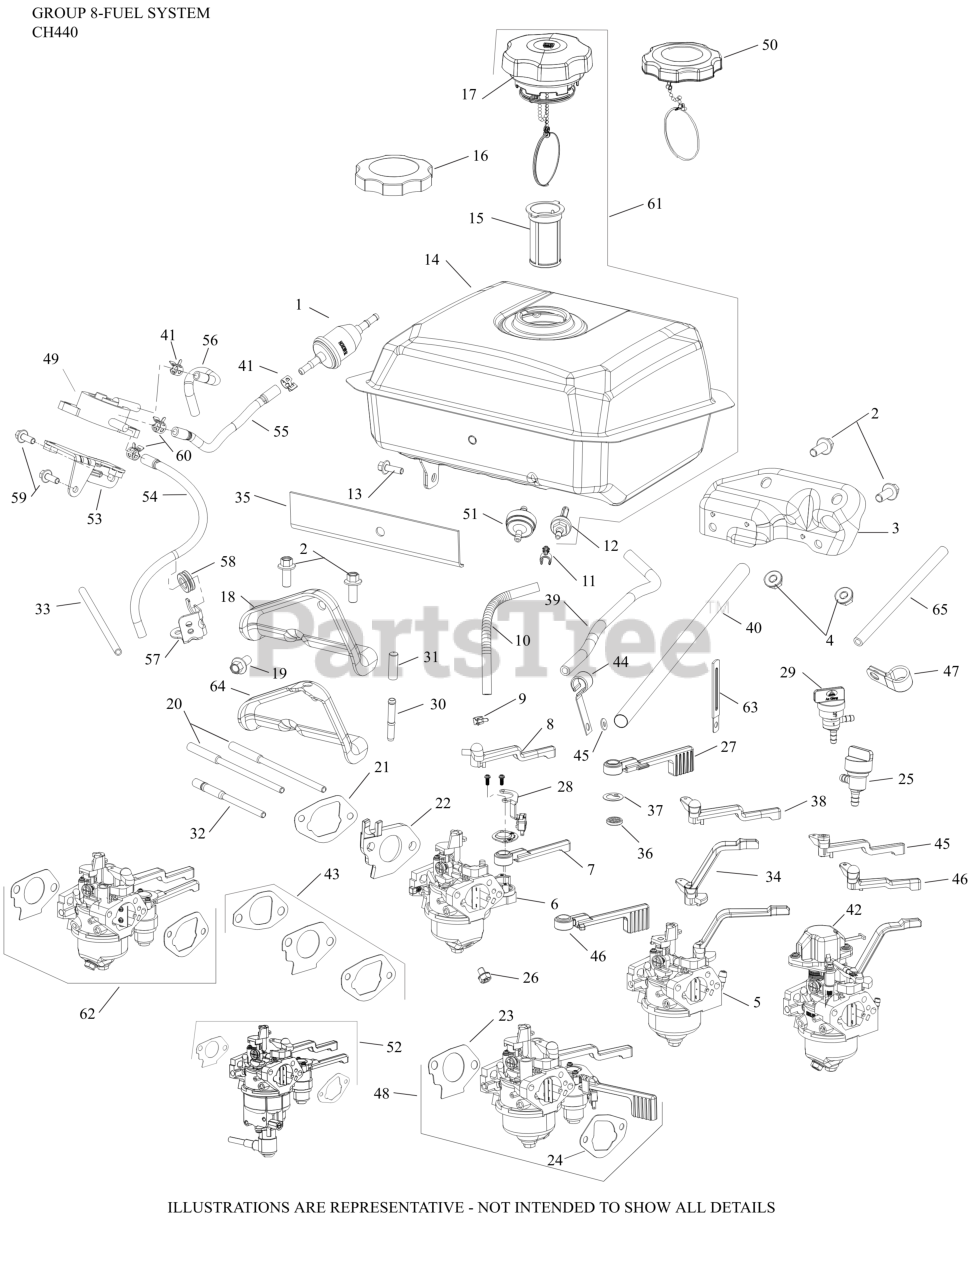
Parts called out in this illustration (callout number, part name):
2	SCREW, M8 X 20
3	BRACKET, FUEL SUPPORT ASSEMBLY
4	NUT, FLG M8X1.25
6	KIT, CARB COMPLETE
7	LEVER, FUEL SHUTOFF
9	CLAMP, FUEL LINE
10	LINE, FUEL (10"-CUT TO LENGTH)
11	CLIP, FUEL HOSE
12	FITTING, FUEL ASSY
14	TANK, FUEL
15	FILTER, FUEL TANK
17	CAP, EVAPORATIVE EMISSIONS-(#1717343S)
17	CAP, FUEL ASSEMBLY
18	BRACKET, FUEL SUPPORT
19	SCREW, FLG 8X1.25X16
20	STUD, CARBURETOR
21	KIT, GASKET INTAKE
22	KIT, INSULATOR
23	GASKET, CARB TO INSULATOR
26	SCREW, BOWL DRAIN
36	SEAL, INLET VALVE
37	KIT, FUEL SCREEN
38	LEVER, CHOKE
47	CLAMP, INSULATED
NI	FUEL CAP, ASSEMBLY-USE 17 173 49-S
NI	KIT, HIGH ALTITUDE (4,000-8,000 FT)
NI	KIT, HIGH ALTITUDE (ABOVE 8,000 FT.)
NI	KIT, CARBURETOR REPAIR
